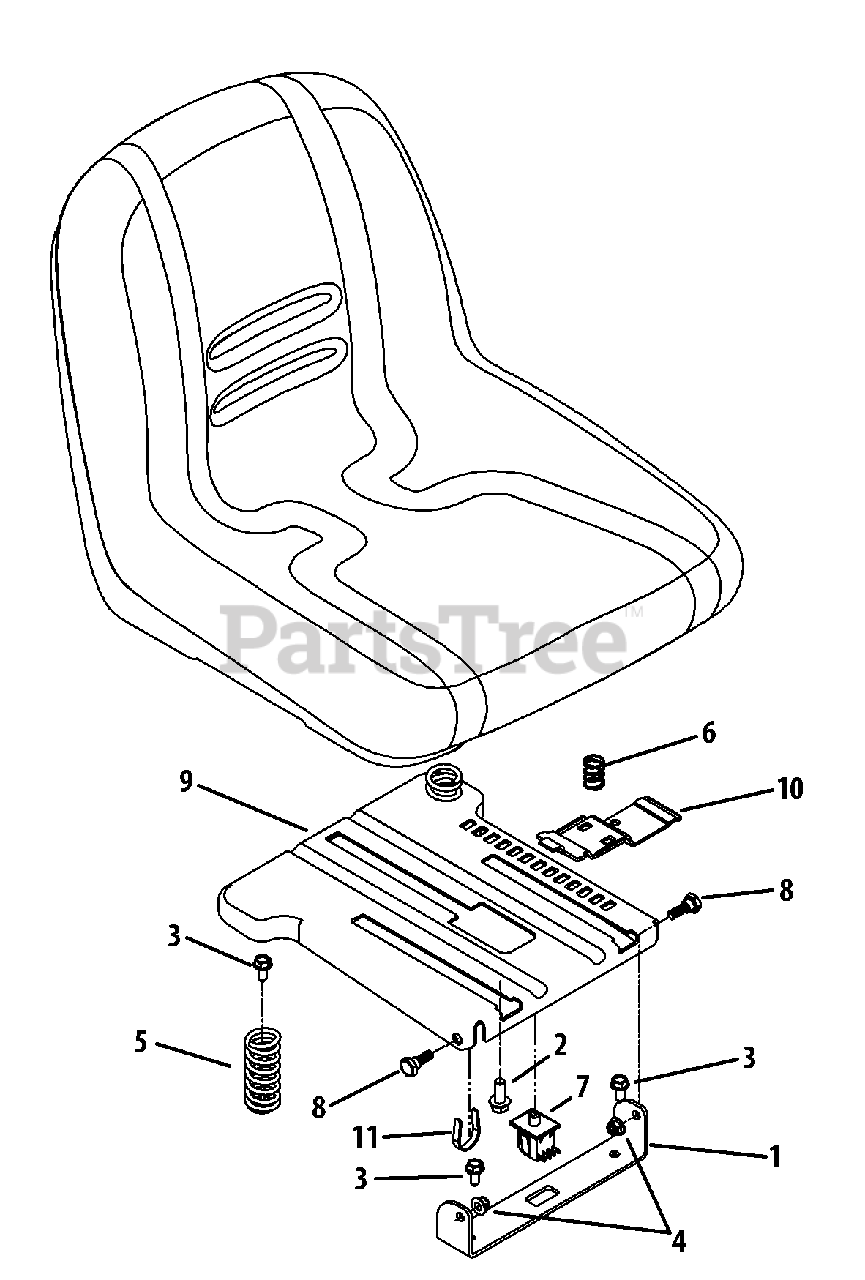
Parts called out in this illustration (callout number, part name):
1	Seat Bracket
2	Hex Flange Bolt, 3/8-16 x .875
3	Hex Washer Screw, 5/16-18 x .750
4	Flange Lock Nut, 5/16-18
5	Compression Spring
6	Compression Spring
7	Switch, Seat
8	Shoulder Screw, .437 x .268 x 5/16-18
9	Seat Mount Bracket
10	Seat Adjustment Lever
